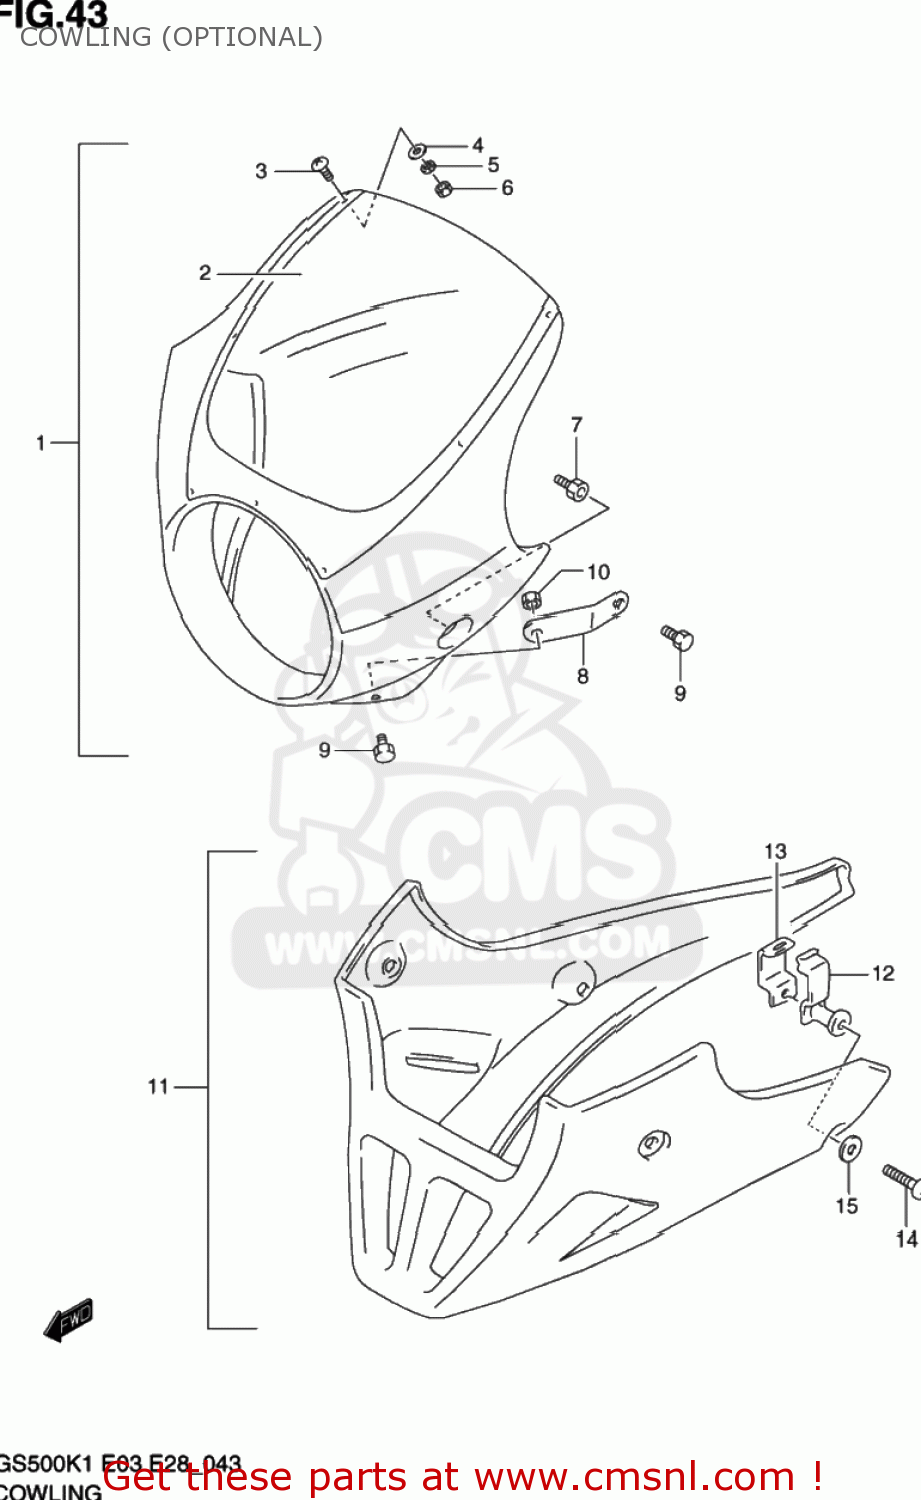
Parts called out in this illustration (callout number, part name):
1	STUURKUIP
2	SCREEN,COWLING
3	SCREW
4	WASHER
5	WASHER,LOCK
6	NUT
7	BOLT,UPR COWLING HEADLAMP
8	BRACE,UPR COWLING
9	BOLT
10	NUT 6MM
11	COVER SET,UNDER COWL
12	BRACKET,UNDER COWLING OUTER
13	BRACKET,UNDER COWLING INNER
14	SCREW
15	WASHER(6.5X18X1.6)
